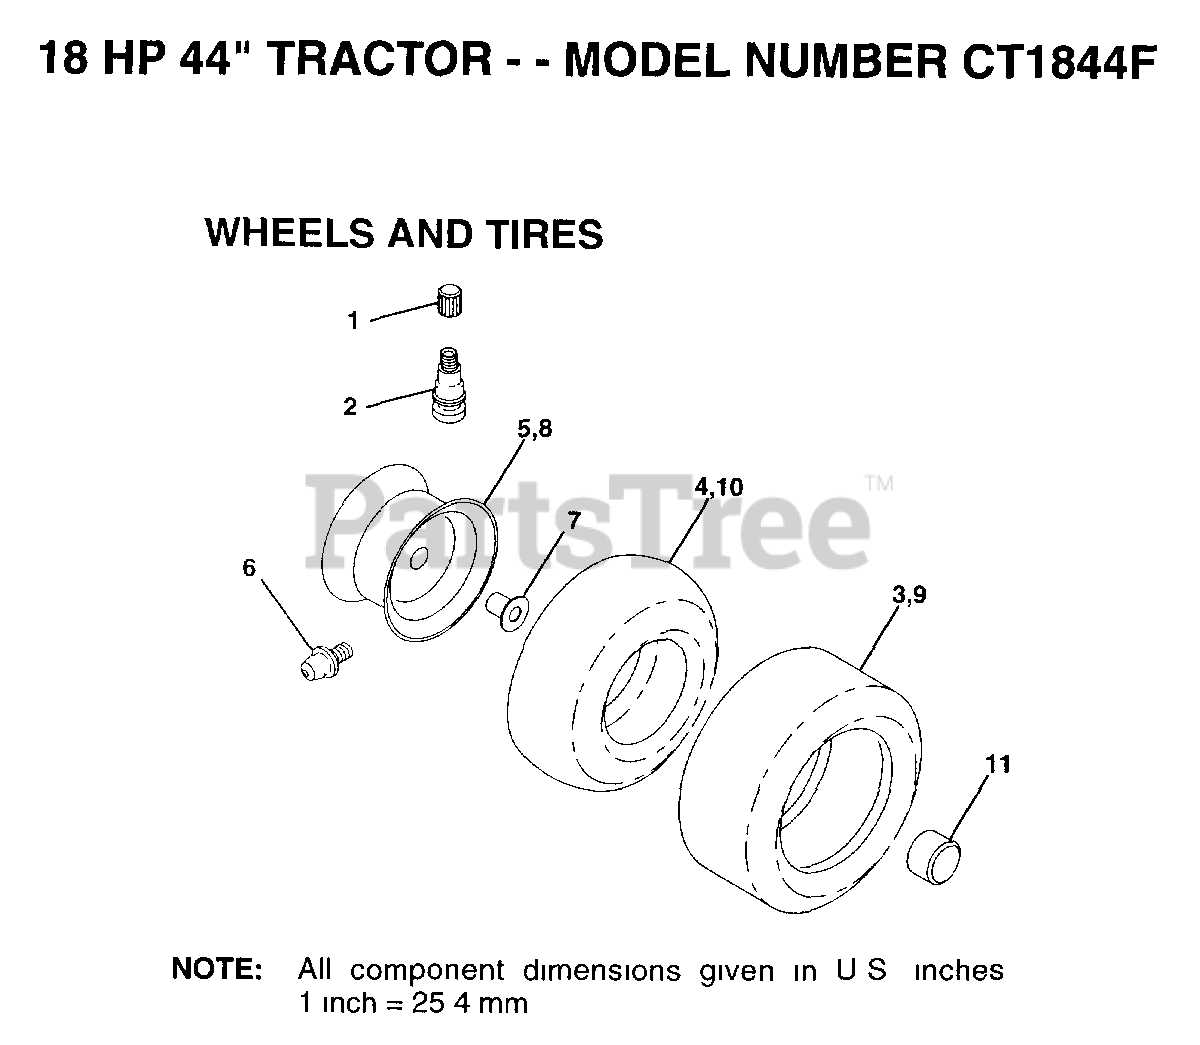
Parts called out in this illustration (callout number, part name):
1	VALVE CAP
2	VALVE STEM LT
4	TUBE.5.3/4.5/6
6	FITTING LT
7	"FLANGE, BEARING"
10	TUBE.18X9.5-8
11	HUB CAP
